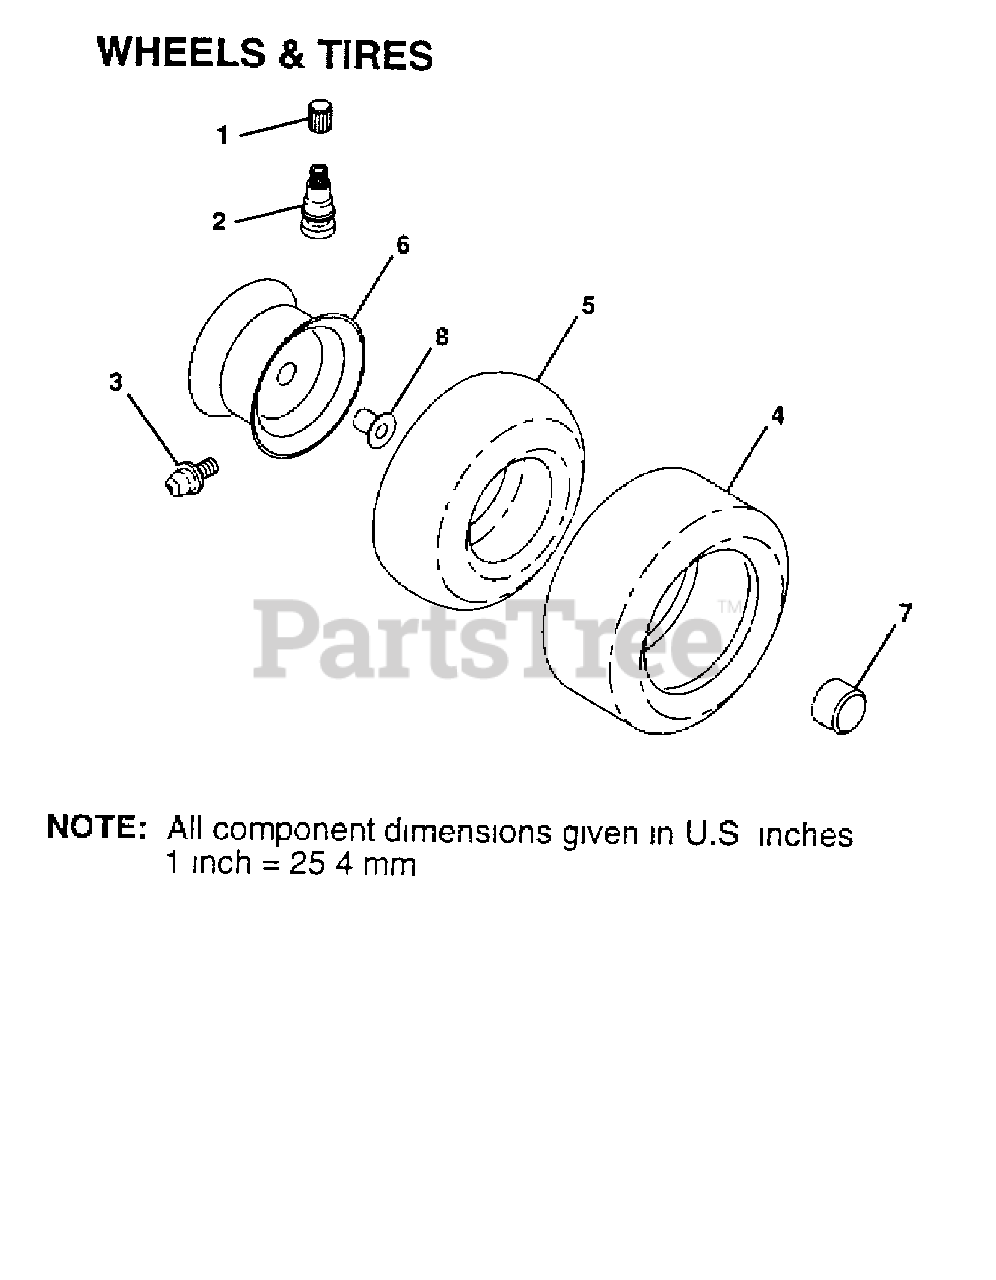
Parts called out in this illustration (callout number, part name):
1	VALVE CAP
2	VALVE STEM LT
3	FITTING LT
4	TIRE HEAVY DUTY
4	TIRE 20X8-8 TURF SAVER
5	TUBE.5.3/4.5/6
5	TUBE - UNIVERSAL FOR 8" RIM
6	RIM.ASM.6".FRONT.SILVER
6	RIM 8" SILVER
7	CAP.HUB.FRONT.LT.BLACK
8	BEARING T
